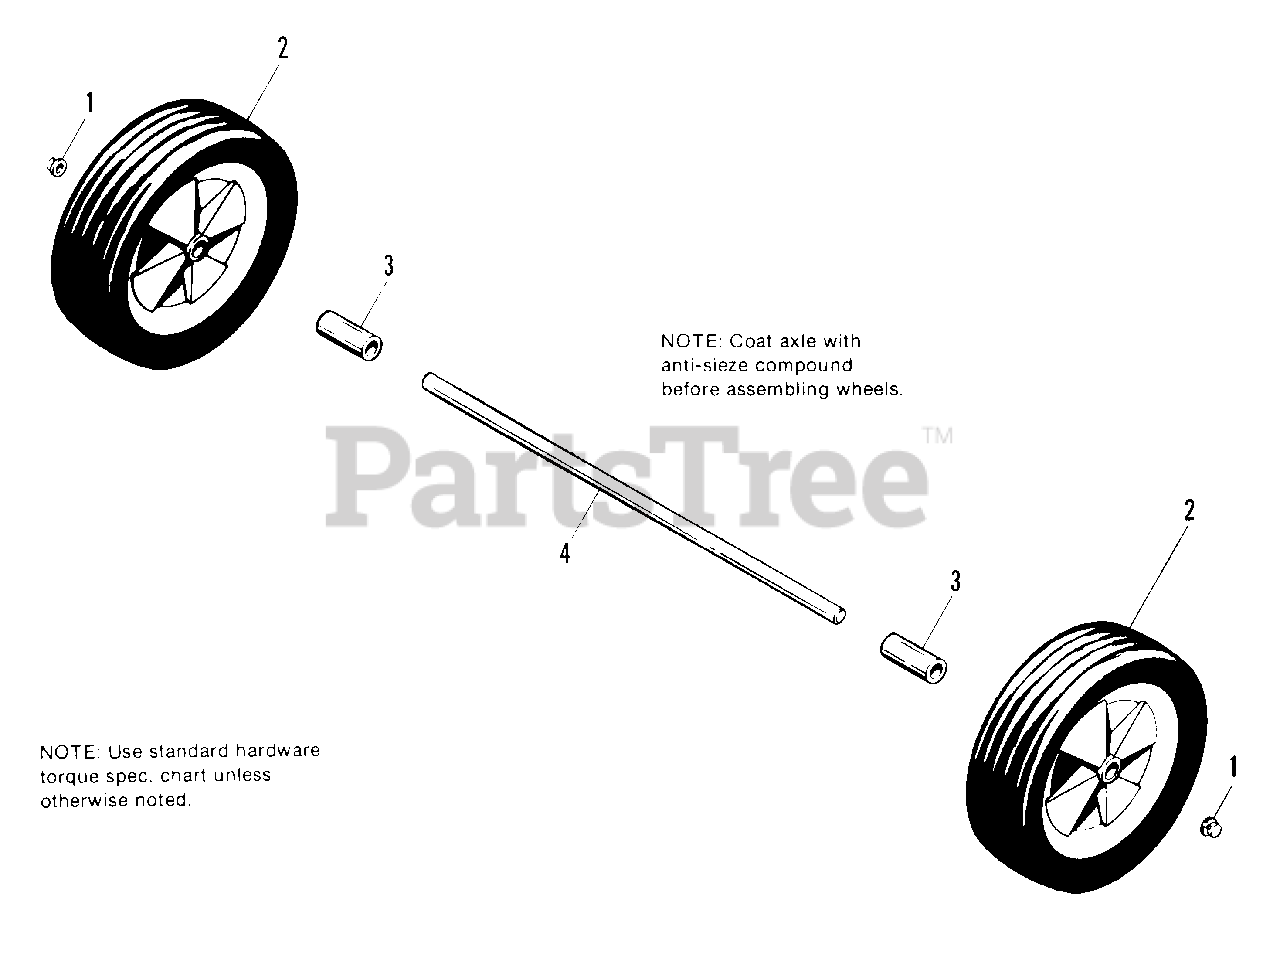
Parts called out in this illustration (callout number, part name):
1	PUSHNUT
2	WHEEL, 10"
3	SPACER, Wheel
